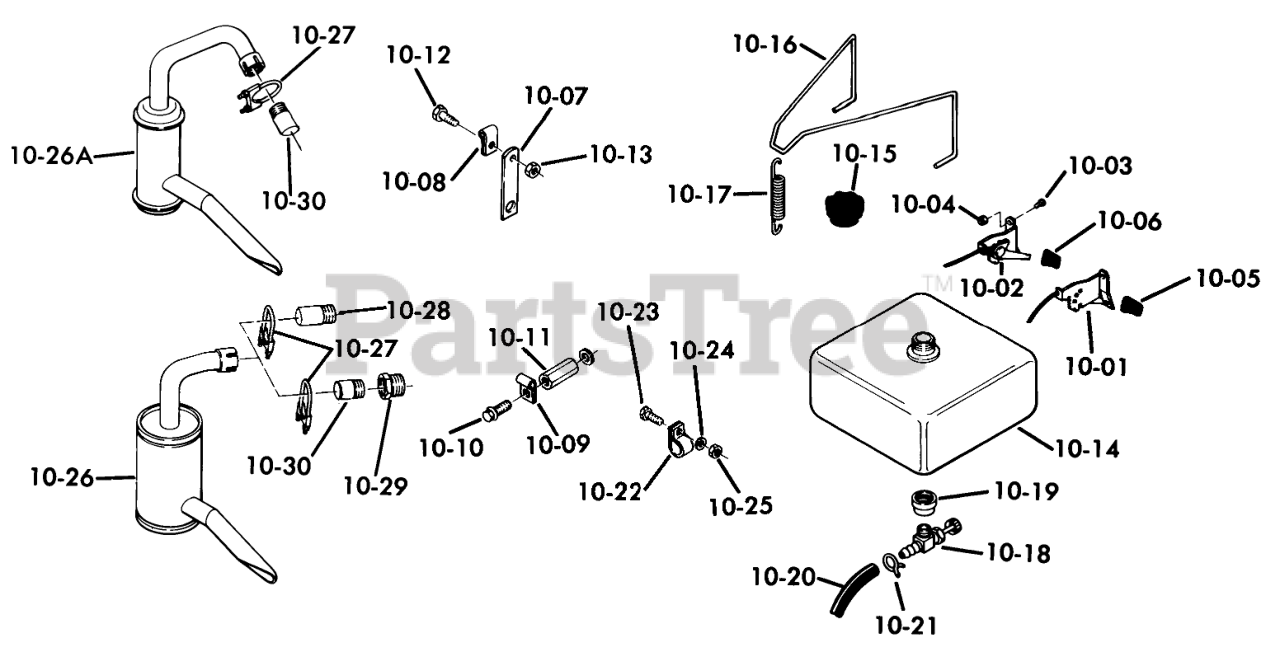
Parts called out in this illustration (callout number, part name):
10-01	Choke Control
10-02	THROTTLE CONTROL
10-02	Screw
10-02	Hex Nut
10-03	SCREW
10-04	#10-24 Kep-Nut
10-05	KNOB-CHOKE
10-06	KNOB-THROTTLE
10-07	Strap
10-08	THROTTLE CONTROL CLP
10-09	Clip
10-10	Screw
10-11	Special Nut
10-12	Screw
10-13	Nut
10-14	ASSY-FUEL TANK
10-15	Cap
10-16	HOLD DOWN WIRE
10-17	CLUTCH SPRING
10-18	VALVE-FUEL
10-19	BUSHING
10-20	Fuel Hose
10-20	Hose-Fuel
10-21	Clamp
10-22	CLAMP-HOSE
10-23	Bolt
10-24	WASHER 5/16 SAE
10-25	Nut
10-26	Muffler
10-26A	Muffler Assy
10-27	ASSY-MUFFLER CLAMP
10-28	NIPPLE
10-29	REDUCER 1 1/4-1
10-30	NIPPLE- 1X2 SPECIAL
